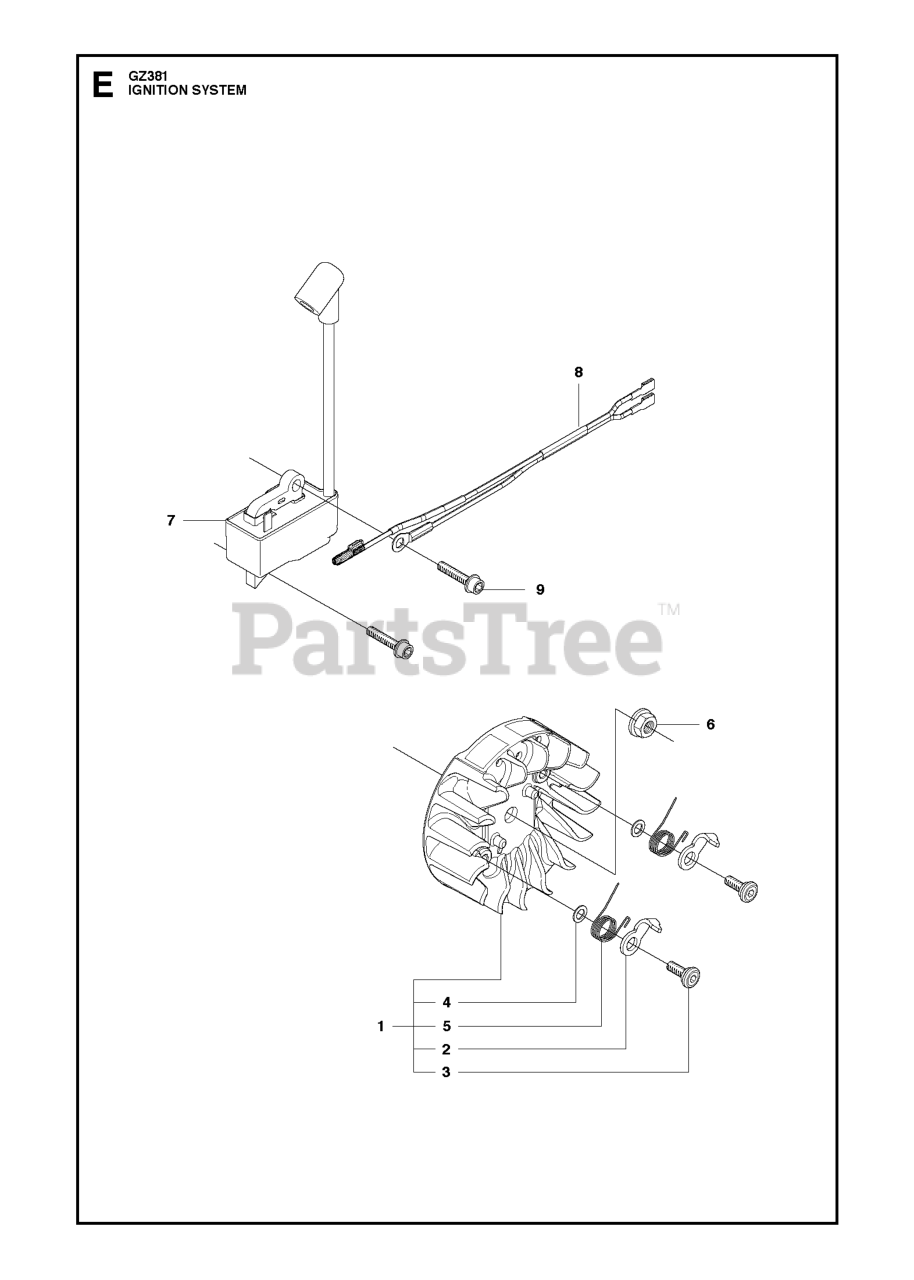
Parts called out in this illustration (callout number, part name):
1	FLYWHEEL ASSY
4	WASHER STEEL
6	NUT W/ WASHER
7	IGNITION MODULE WALBRO MBU
8	WIRING ASSY
